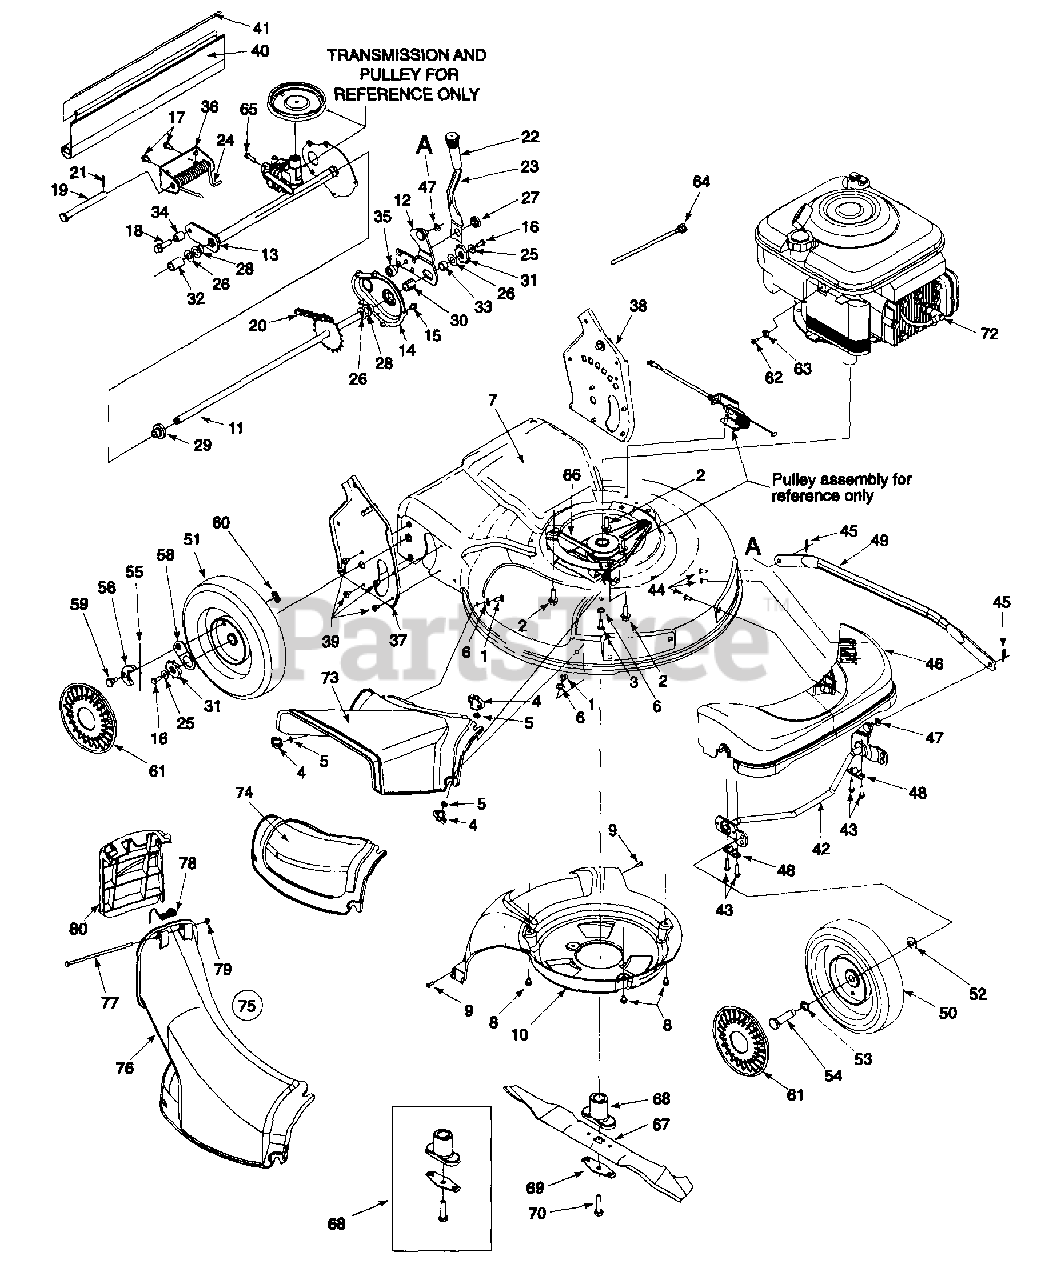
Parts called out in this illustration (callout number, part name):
1	Scr. Carr. 1/4-20 x .62
2	Scr. TT: 3/8-18: 1.00
3	Scr. 1/4-20 x .750
4	Wing Nut 1/4-20
5	Nut, Push.25 I.D. x .50 O.D.
6	Wash. Fl. .334 I.D. x .62 x.03
7	Deck - 21"
8	Scr. TT. 1/4-20 x .375
9	Scr. HL. 1/2-14 x .750
10	Baffle
11	Rear Axle Ass'y
16	Cap Screw HH 1/4-20 x .620
17	Scr. AB 1/4-14 x .825
18	Scr. 3/8 116 x .25
19	Clevis Pin .50 Dia. x 4.82 Lg.
20	Chain-Endls. #48 .500P x 24 L
21	Cotter Pin .125 O.D. x .75
23	Spring Lever
24	Torsion Spring
25	Bell Wash. .285 x .75 x .082
26	Fl. Wash. .508 I.D. 1.000 x .
27	Nut Shld. .825 Dia. x .165 Lg.
28	Hx.Flg. Brg. .506 I.D. x.590 L.
29	Hx.Flg. Brg. .506 I.D. x.715 L.
30	Hx. Slv. Brg. .504 I.D. x.830 L.
31	Wheel Rachet
32	Spa. .550 I.D. x .750 O.D.
33	Spa. .51 .D. x .70 O.D. x 38 L.
34	Spa. .385 x .624 x .700
35	Shld. Spa. .385 I.D. X.715 Lg.
38	Handle Brkt. Ass'y. L.H.
39	Scr. AB 1/4-14 x .500
40	Trail Shield
41	Trail Shield Wire
42	Fr. Axle Ass'y.
43	Hx Scr. Wash Hd. Hi.-Lo.
44	Scr. Torx, Truss Hi.-Lo.
45	Cotter Pin .072 x 1.12 Lg.
46	Fr. Axle Cover, Yellow
47	Bowed Washer
48	Bush. Block .505 Dia. x .62
49	Control Arm
50	Wheel 8 x 2 Link, Yellow
51	Wheel 9 x 2 Link, Yellow Slv.
52	Spr. Wash. .401 x .870 x .063
53	Wave Wash .510 x .750 x .017
54	Shldr Scr .498 x 1.445 x 3/8-16
55	Spring, Ratchet, Plastic
56	Pawl - R.H.
56	Pawl - L.H.
58	Ratchet Pawl Plate
59	Scr. Shld. .340 x .285
60	Top Lock Tab Weld Nut 1/4-20
61	Hubcap -Yellow
62	Screw .620 Hx. Slt. Wsh.
63	Casing Clamp, Throttle
64	Cable Tie
65	Hex Scr. 5/16-18
66	Belt
67	21" Mulching Blade
68	Blade Adapter Kit
69	Blade Bell Support
70	Hex Bolt 3/8-24 x 2.5" Lg.
72	Spark Plug Insulator
73	Side Discharge Chute
74	Mulch Cover
75	Chute Ass'y
76	Discharge Chute
77	Pivot Rod
78	Torsion Spring
79	Push Cap
80	Chute Door
